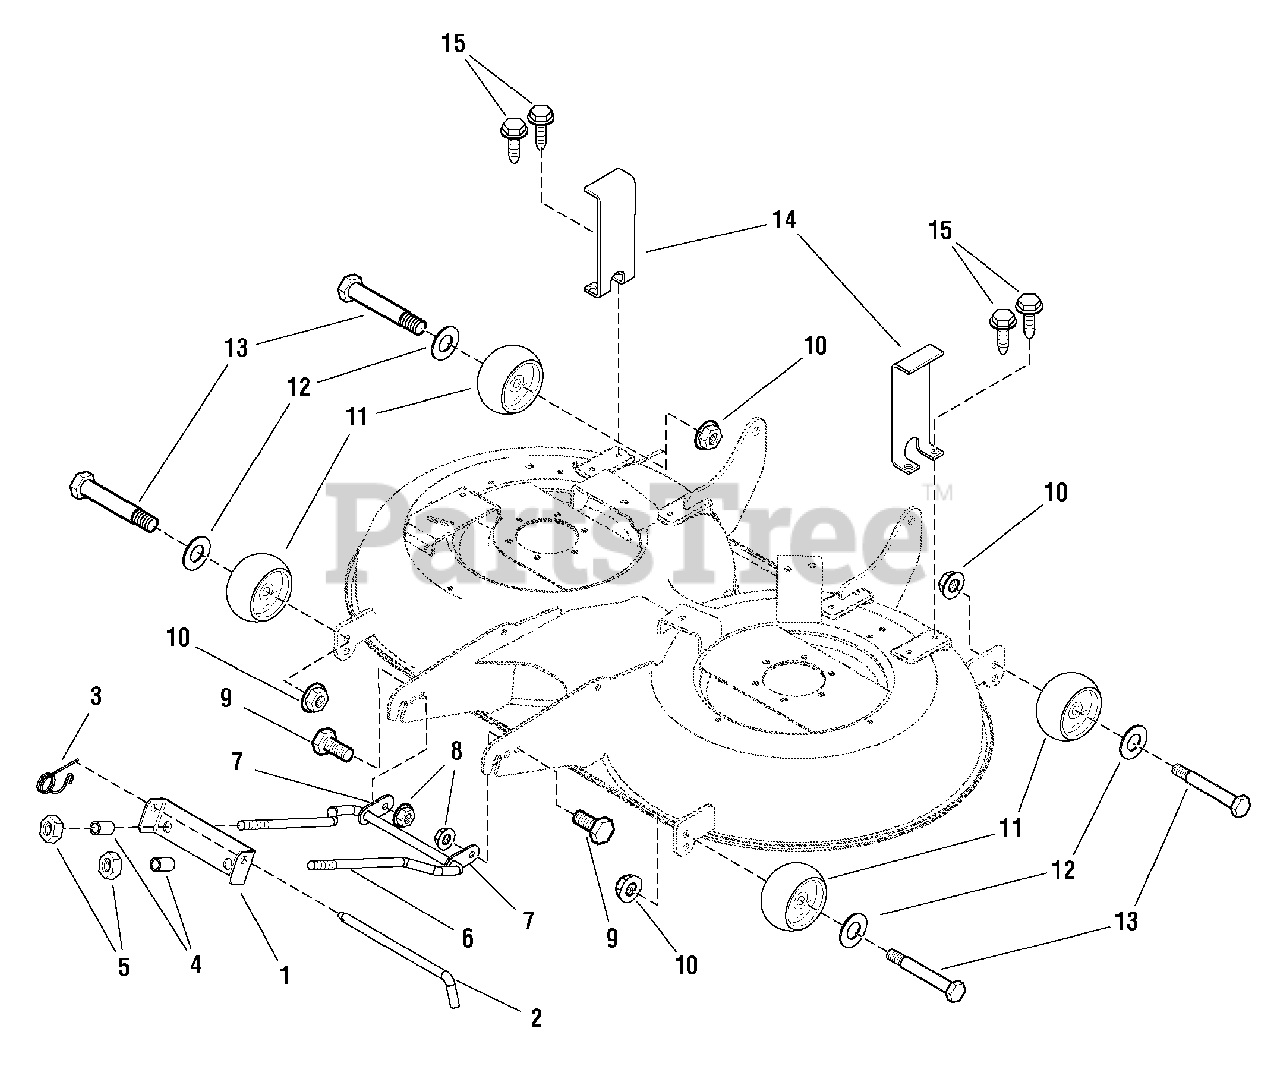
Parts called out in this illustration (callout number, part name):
1	HANGER, Front
2	PIN, Hitch
3	RETAINER, Pin Spring
4	SPACER
5	NUT, Hex Lock ESNA Light, 1/2-13 ,Thin
6	ROD, Bail
7	PLATE, Pivot Lock
8	NUT, Hex Flange 5/16-18, Whiz Lock
9	SCREW, Hex Flange 5/16-18 x 3/4
10	NUT, Hex Flange ESNA 3/8-16
11	WHEEL
12	WASHER, Flat 3/8
13	BOLT, Wheel 3/8-16 x 2.781
14	UPSTOP
15	SCREW, Taptite 5/16-18 x 3/4
